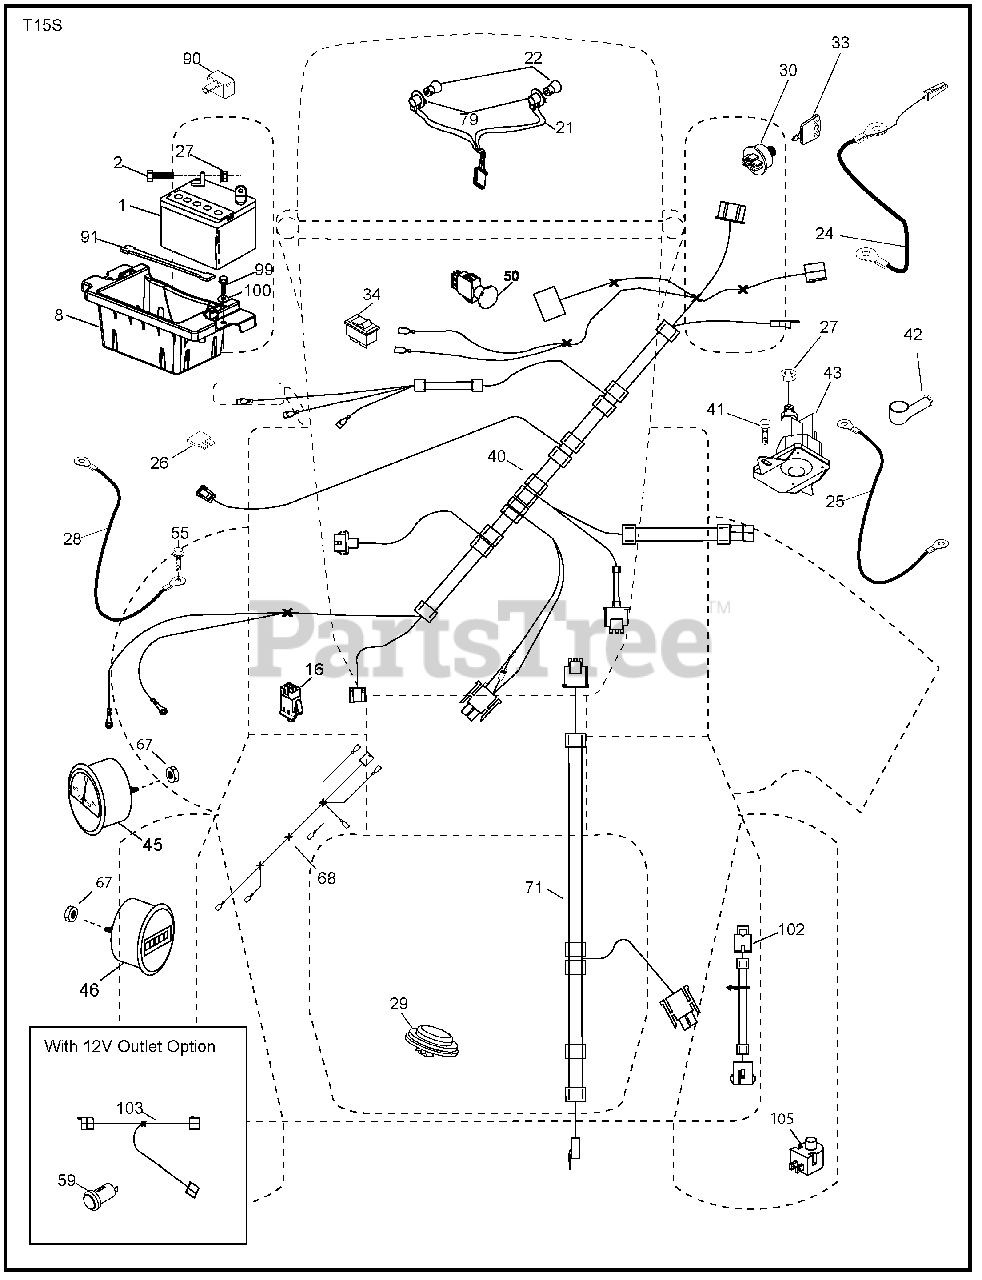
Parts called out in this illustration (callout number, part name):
1	Battery
2	Bolt Hex Head 1/4-20 x 3/4
8	Tray Battery Frt Tex Carb
16	Switch Interlock Push-In
21	Harness Socket Light w/4152J
22	Bulb Light
24	Cable Battery
25	Cable Starter
27	Nut Keps Hex 1/4-20 unc
28	Cable, Ground
29	Switch, Seat
30	Switch, Ign
34	Switch Light / Reset
40	Harness Ign. Dash
41	Screw Thd Cut 1/4-20 x 1/2
42	Cover, Terminal
43	Solenoid
45	Ammeter Studmount LS
46	Hourmeter Studmount LS
50	Switch PTO
55	Screw Thdrol 5/16-18 x 3/4 TYTT
59	Outlet 12-Volt
67	Nut 10-32 Ext Lock
68	Harness Jumper Gauges
71	Harness Ign.
79	Socket Asm Bulb Twistlock
90	Cover Terminal
91	Strap Battery Mount
99	Screw Hexwsh Thdrol 1/4-20 x 3/4
100	Washer 9/32 x 7/8 x 16 Ga.
102	Harness Pigtail
103	Harness 12-Volt Pigtail
105	Switch Reverse TT Pedal Control
